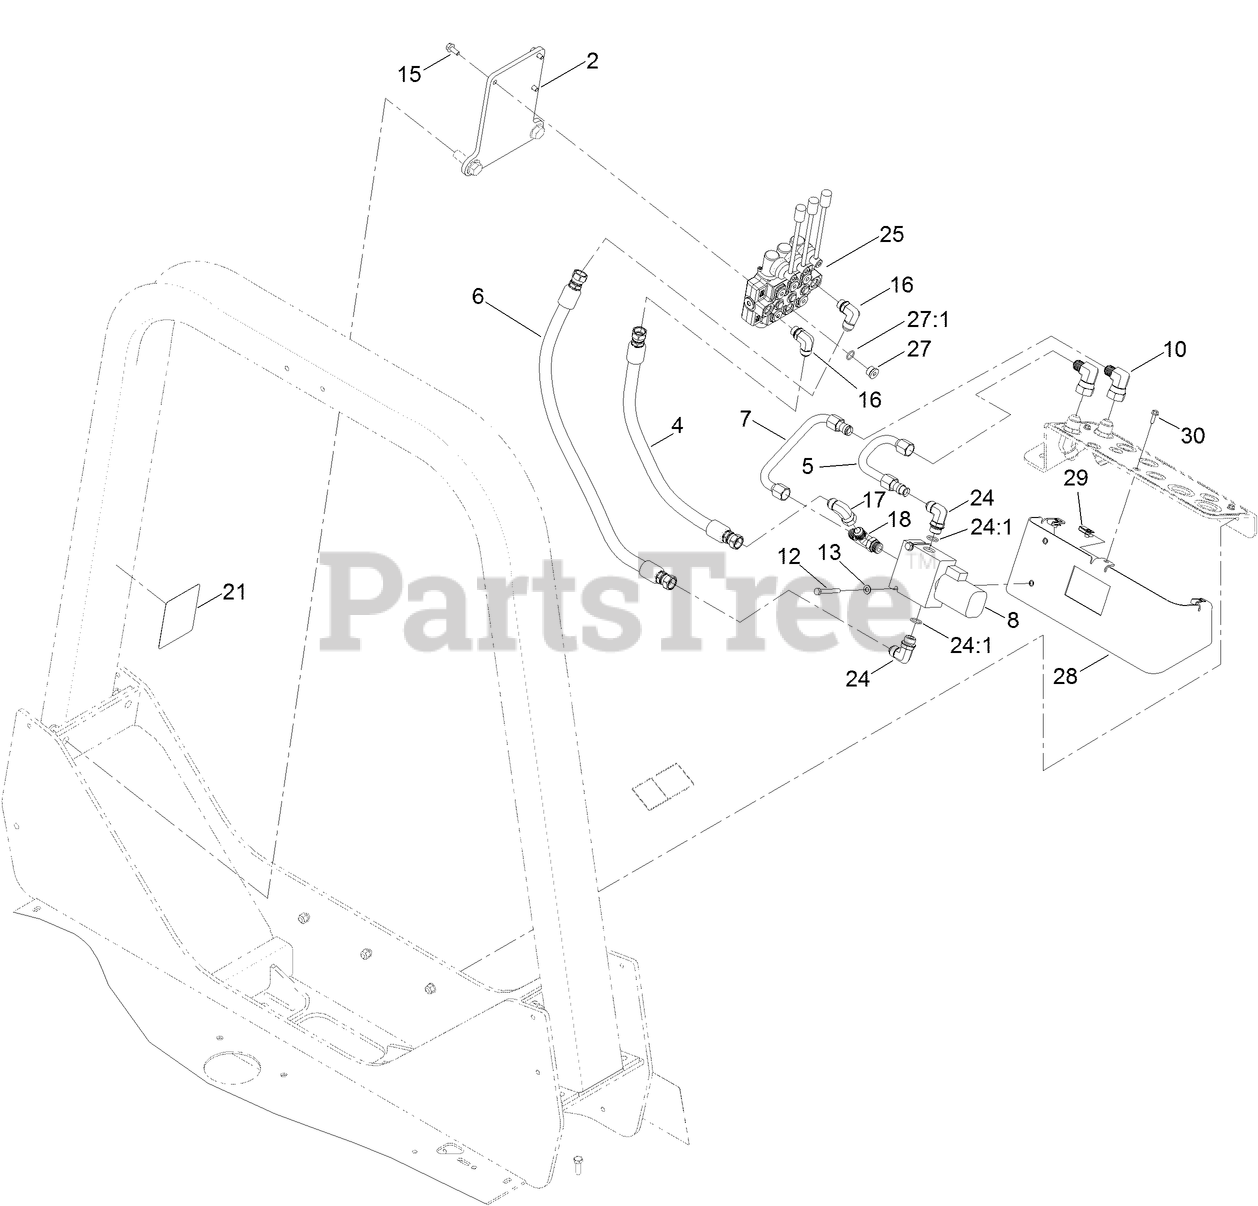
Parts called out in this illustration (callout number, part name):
2	PLATE-MOUNT, VALVE
4	HOSE ASM-HYD HP
5	TUBE ASM-HYD
6	HOSE ASM-HYD HP
7	TUBE ASM-HYD
8	DIRECTIONAL VALVE ASM
10	FITTING-ELBOW, 90
12	SCREW-HH
13	WASHER-PLAIN
15	SCREW-HHF
16	ADAPTER
17	ADAPTOR
18	FITTING-TEE
21	DECAL-VALVE, AUXILIARY
24	FITTING-ELBOW, 90 DEG
24:1	O-RING
25	VALVE-Auxiliary
27	PLUG-HEX
27:1	O-RING
28	COVER ASM
30	SCREW-HHF
